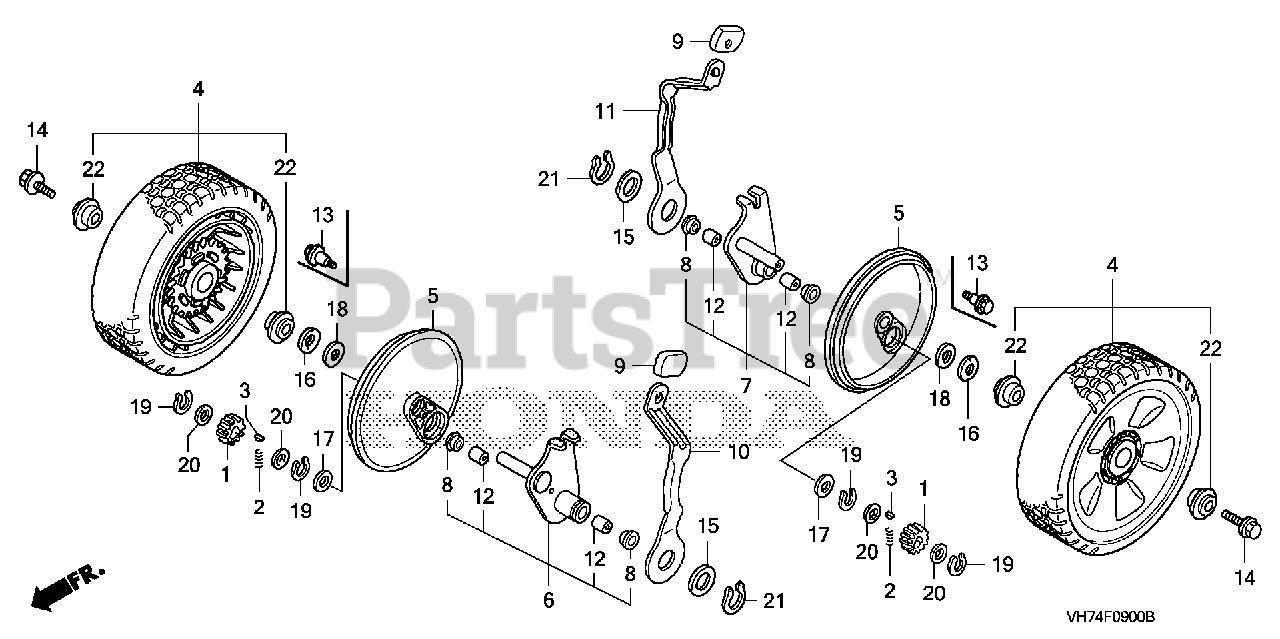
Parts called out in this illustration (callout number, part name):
1	GEAR, PINION (13T)
2	SPRING, RATCHET RETURN
3	KEY, RATCHET
4	WHEEL, RR. *NH164* (GRIP GRAY)
6	ARM, R. RR. ADJUSTING
7	ARM, L. RR. ADJUSTING
8	DUST SEAL (12.7MM)
9	GRIP, ADJUSTER
9	GRIP, ADJUSTER *NH105* (MAT BLACK)
10	PLATE, R. RR. ADJUSTING
11	PLATE, L. RR. ADJUSTING
12	BUSH, DRIVESHAFT
13	SCREW, TAPPING (5X12)
14	BOLT, WHEEL
15	WASHER, PLAIN (22MM)
16	WASHER, WHEEL
17	WASHER, THRUST (13MM)
18	WASHER, THRUST (13X27X1)
19	CIRCLIP (OUTER) (12.7MM)
20	COLLAR, PINION GEAR
21	CIRCLIP (OUTER) (22MM)
22	BEARING, RADIAL BALL
22	BEARING, WHEEL
